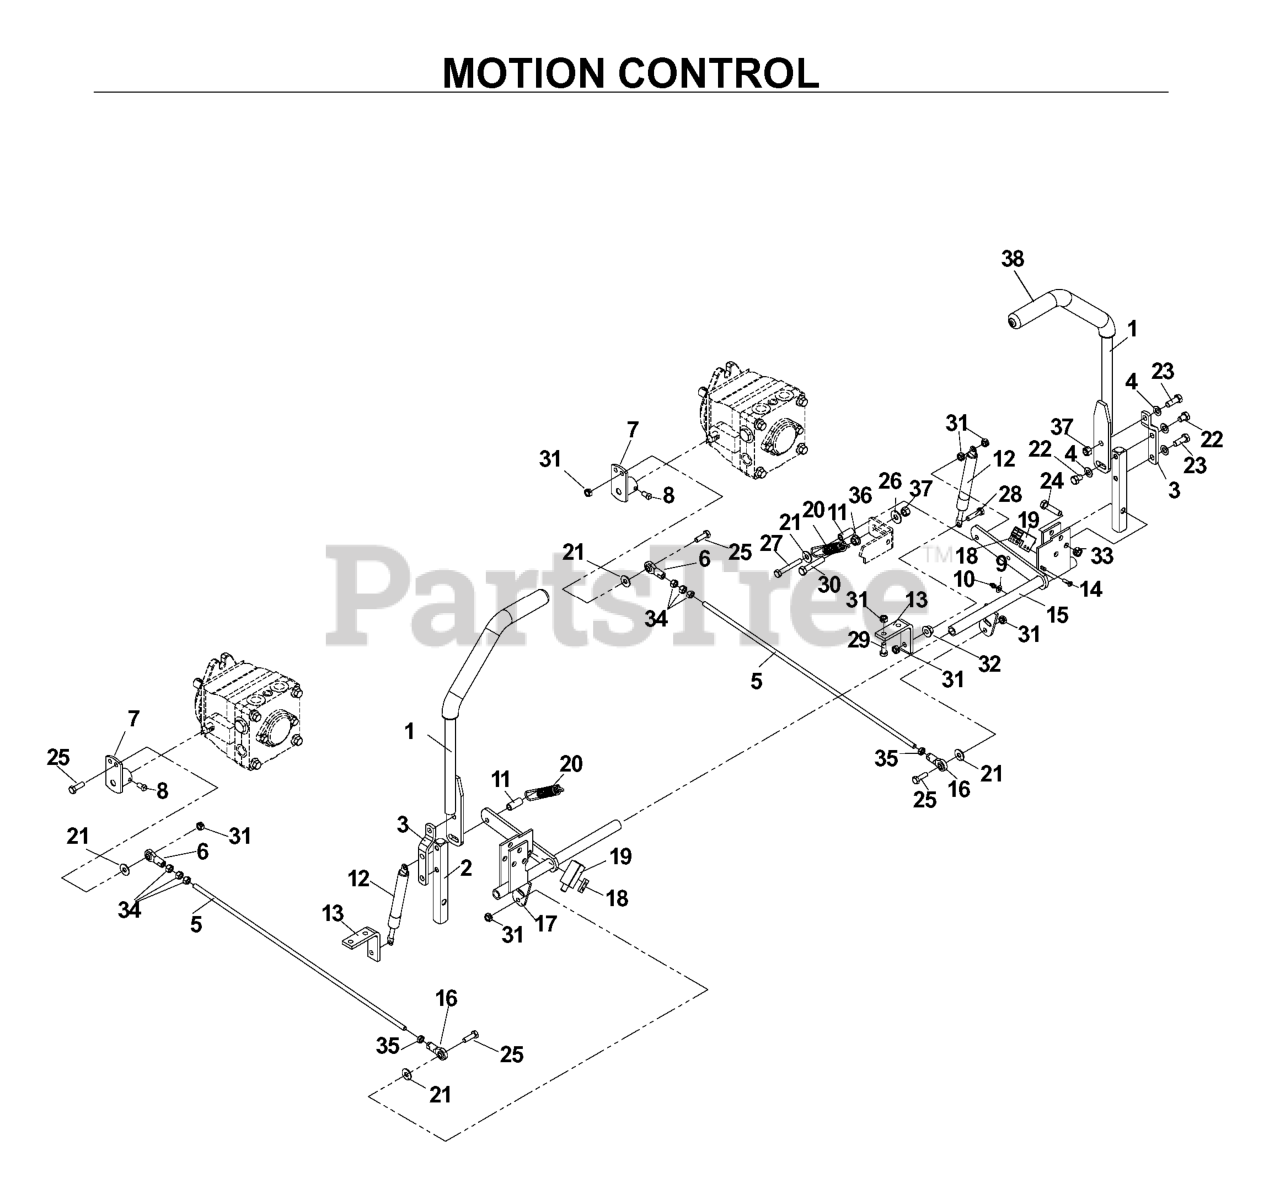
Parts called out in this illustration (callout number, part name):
1	CONTROL LEVER WELDMENT
2	CONTROL ARM
3	CONTROL LEVER EXT
4	WASHER, 3/8 DISC SPRING SPEC
5	PUMP LINKAGE BAR
6	BALL JOINT, RIGHT HANDED
7	PUMP LEVER
8	5/16C X 5/8 "V" POINT
10	ZERK
13	L BRACKET-PAINTED
14	SCREW #10-24 X 5/8
15	CONTROL WELDMENT LT
16	BALL JOINT, LEFT HANDED
17	CONTROL WELDMENT RT.
18	TAPPED PLATE
21	WASHER 5/16 FLAT
22	BOLT .375 X .5
23	HCS 3/8-16X1.GRD.5.ZD
24	HCS 3/8C X 1 1/2
25	HCS 5/16C X 1
26	WASHER 3/8 FLAT
27	TAP BOLT 5/16C X 2 1/4
28	HCS 5/16C X 1 1/4
29	HCS 5/16C X 3/4
30	HCS 3/8C X 2
31	NUT 5/16C CENTERLOCK
32	NUT 5/16C WHIZ
33	NUT 3/8C CENTERBLOCK
35	NUT 5/16F LEFTHAND
36	NUT 3/8C WHIZ
37	NUT 3/8-16 NYLOC
